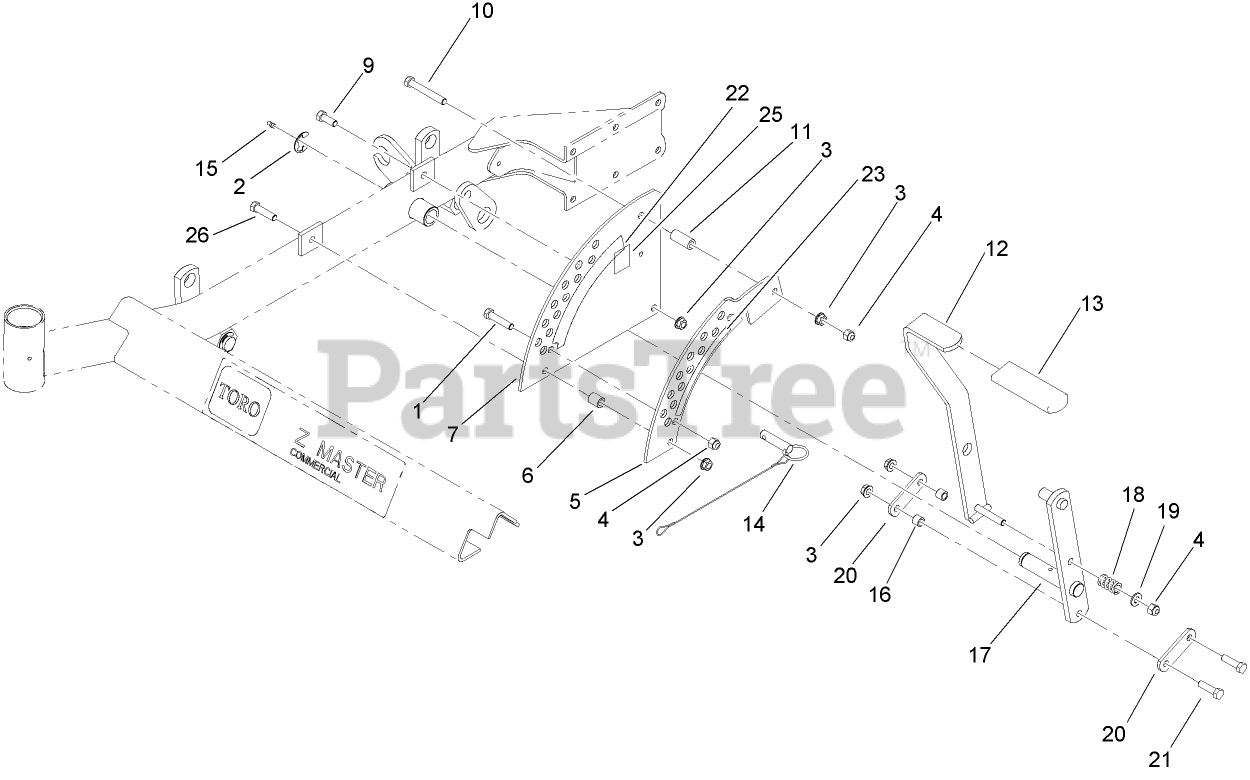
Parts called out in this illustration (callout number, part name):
1	SCREW-HH
2	RING-RETAINING, EXT
3	NUT-HHF, WHIZ
4	NUT-LOCK, NI
5	PLATE-LIFT, DECK
6	BUSHING-LEVER, LIFT
7	PLATE-LIFT, DECK
9	SCREW-HH
10	SCREW-HH
11	BUSHING-LEVER, LIFT
12	HANDLE-LIFT
13	GRIP-LEVER, LIFT
14	Hitch Pin ASM
15	FITTING-GREASE
16	Bushing
17	LIFT ARM ASM
18	SPRING-COMPRESSION
19	WASHER-FLAT
20	ARM-LIFT, DECK
21	SCREW-HH
22	DECAL-DECK HEIGHT, OUTER
23	DECAL-DECK HEIGHT, INNER
25	DECAL-NOISE
26	SCREW-HH
